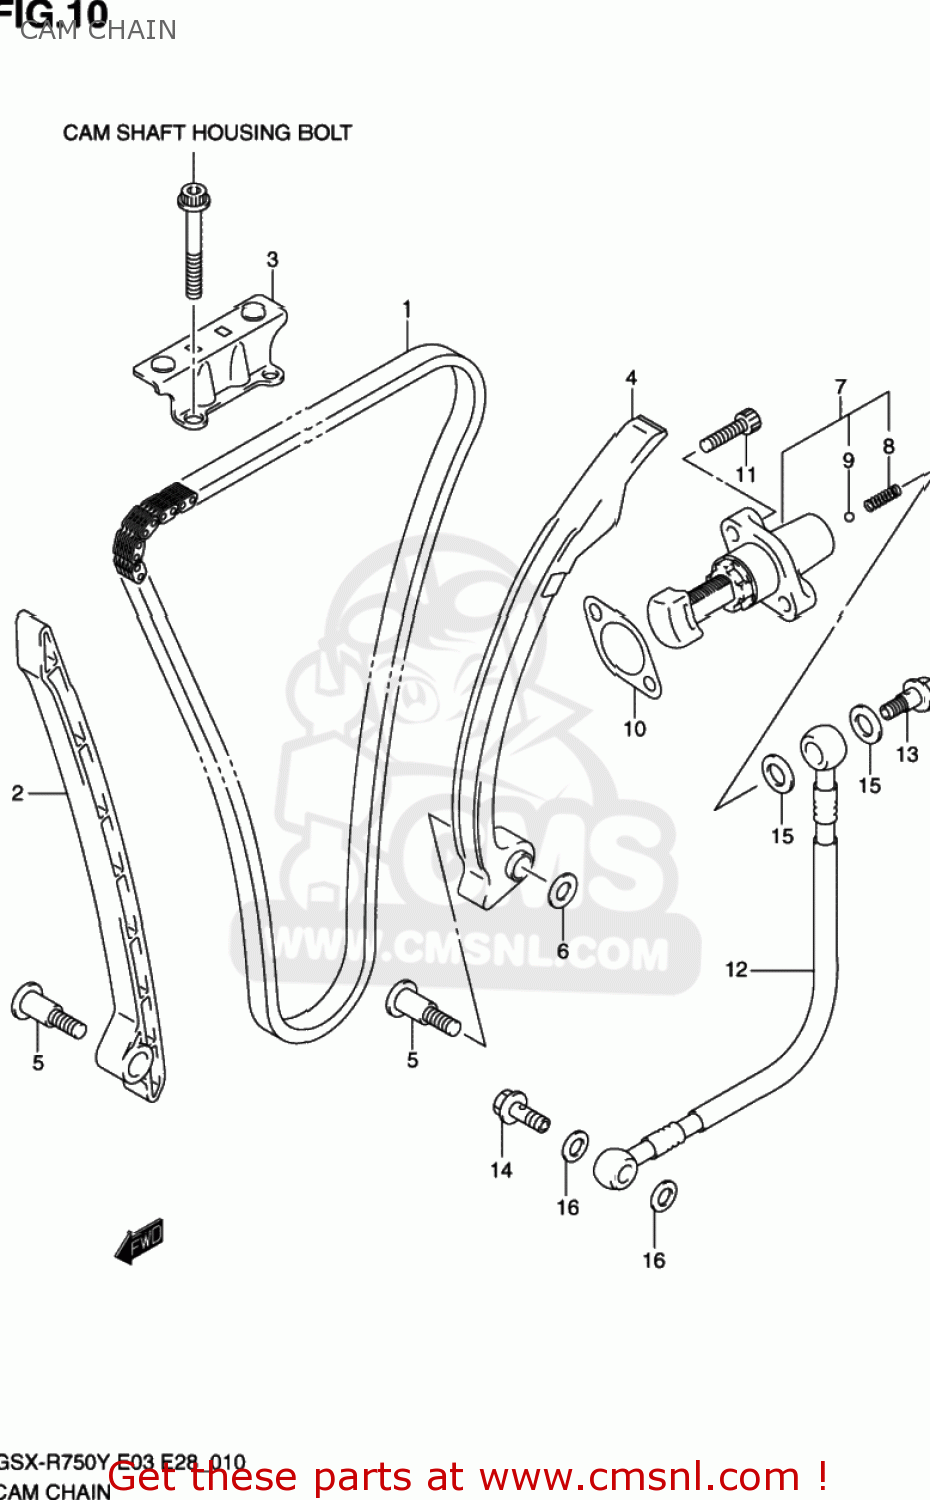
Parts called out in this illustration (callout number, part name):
1	CHAIN COMP,CAMSHAFT DRIVE
2	GUIDE,CAM CHAIN NO.1
3	GUIDE,CAM CHAIN NO.2
4	TENSIONER,CAM CHAIN
5	BOLT,CAM CHAIN TENSIONER/GUIDE
6	WASHER
7	ADJUSTER ASSEMBLY,TENSIONER
8	SPRING
9	BALL
10	GASKET,TENSIONER ADJUSTER (NAS)
11	BOLT,CL.COVER
12	HOSE,TENSIONER ADJUSTER
13	BOLT,ADJ OIL HOSE UNION NO,1
14	BOLT,ADJUST OIL HOSE UNION
15	GASKET(12X17X1) (NAS)
16	GASKET 8.2X14X1 (NAS)
